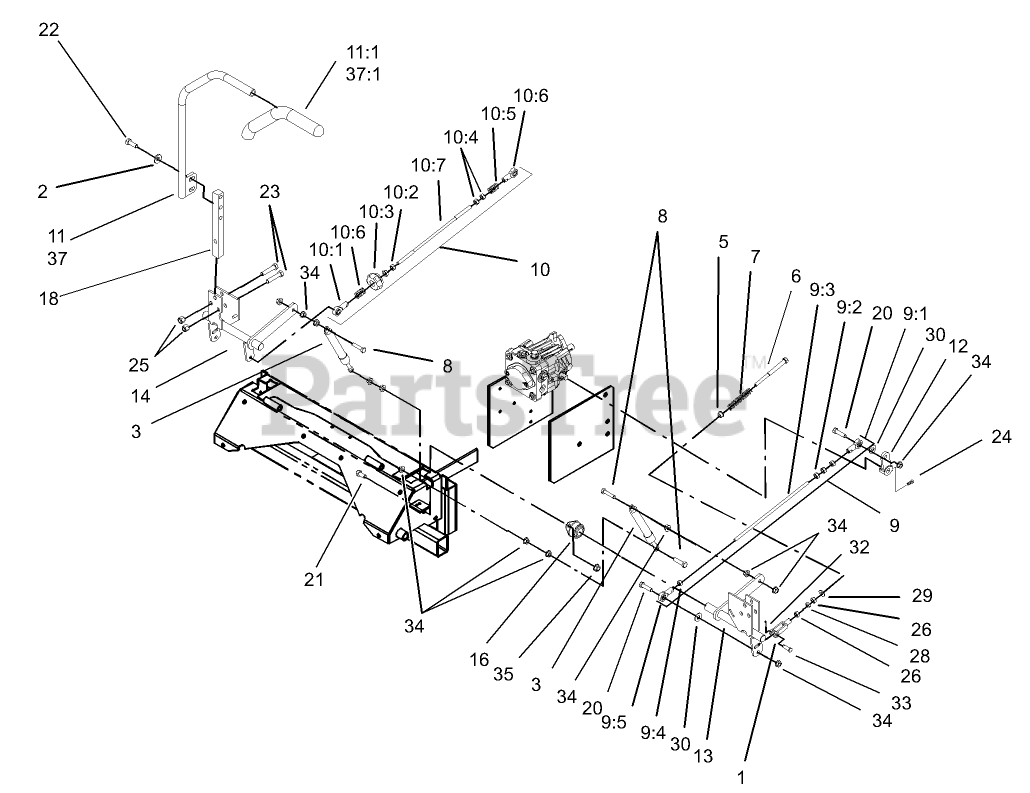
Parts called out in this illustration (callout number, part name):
1	YOKE-ADJUSTABLE
2	WASHER-BELLEVILLE
3	Damper-Control, Motion
5	BUSHING-FLANGED
6	BOLT-RETURN, NEUTRAL
7	SPRING-RETURN, NEUTRAL
8	SCREW-HH
9	LH Pump Linkage ASM
9:1	BALLJOINT-RH
9:2	NUT-HEX
9:3	Link-Rod, Tracking
9:5	BALLJOINT-LH
10	Tracking Rod ASM
10:1	BALLJOINT-RH
10:2	NUT-HEX
10:3	KNOB-TRACKING
10:5	SPRING-COMPRESSION
10:6	BALLJOINT-LH
10:7	Link-Rod, Tracking
11	RH LEVER ASM
11:1	GRIP-CONTROL, MOTION
12	ARM-CONTROL, PUMP
13	CONTROL-MOTION, LH
14	CONTROL-MOTION, RH
16	BEARING-FLANGE, SIDE
18	ARM-SHAFT, CONTROL
20	SCREW-HH
21	SCREW-HH
22	SCREW-HH
23	SCREW-HH
24	SCREW-SET
25	NUT-LOCK, NI
26	NUT-HEX
28	NUT-JAM
29	WASHER-FLAT
30	WASHER-FLAT
32	PIN-COTTER
33	PIN-CLEVIS
34	NUT-HF
35	NUT-HHF, WHIZ
37	LH LEVER ASM
37:1	GRIP-CONTROL, MOTION
